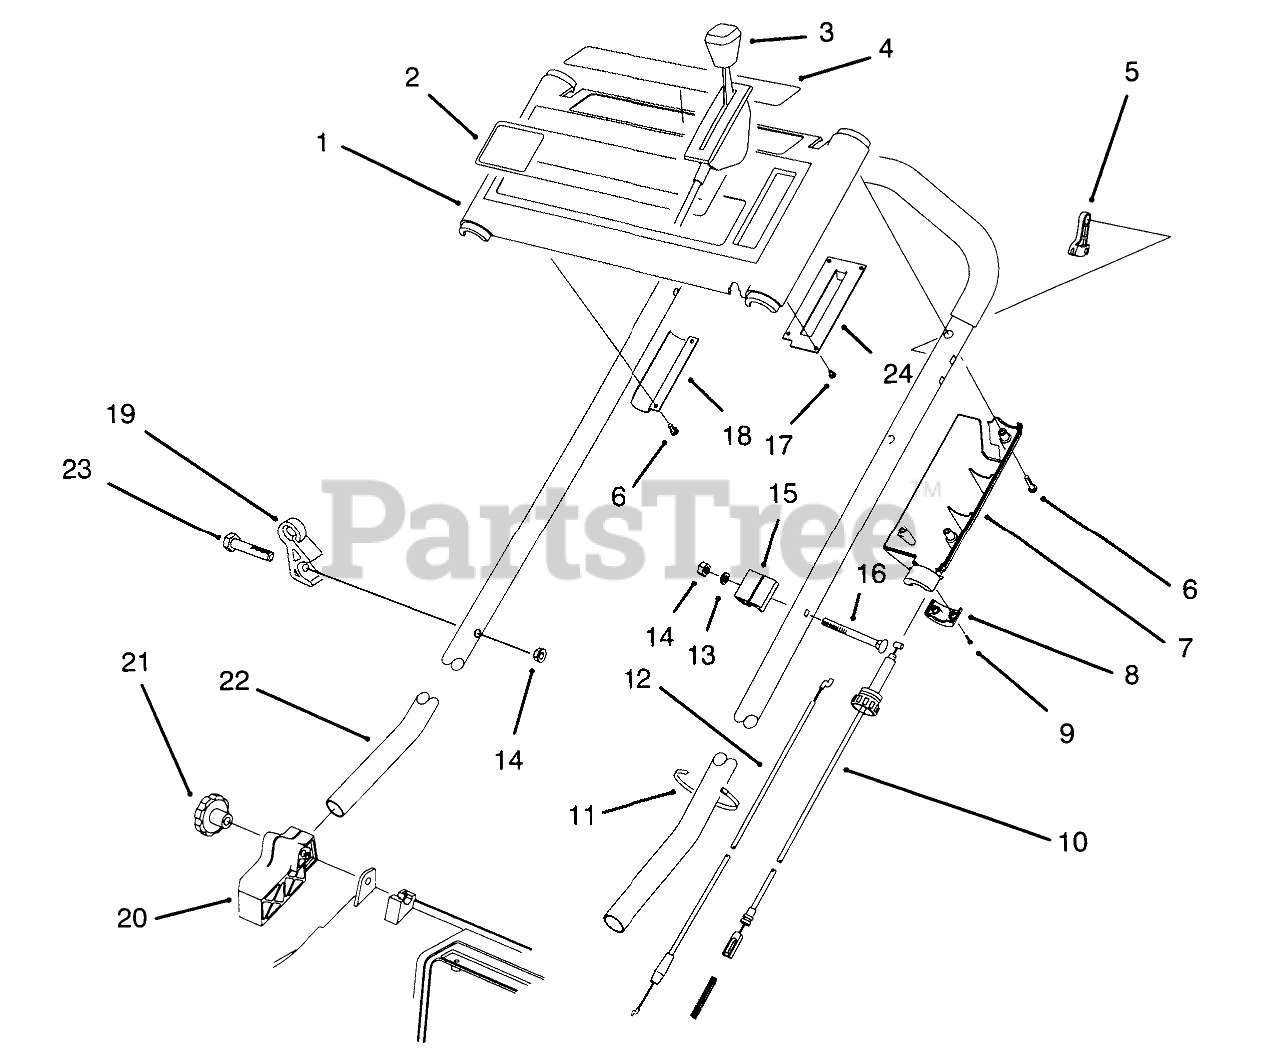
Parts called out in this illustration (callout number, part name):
1	Panel-Control(Incl Ref. #2,4)
2	DECAL - PANEL OHV
3	CONTROL - THROTTLE
4	DECAL - INSTRUCTION
5	LEVER-TRACTION
6	SCREW-PPH, PLASTITE
7	COVER-THROTTLE, LEVER
8	LOWER THROTTLE CAP
9	#4-14X.62 PLASTITE SCW
10	CABLE - TRACTION
11	TIE-CABLE
12	CABLE - BRAKE
13	WASHER-FLAT
14	NUT-LOCK, NI
15	SUPPORT-CABLE
16	SCREW-HANDLE
17	#6-19X.25 PLASK FORM SC
18	Bracket-Panel
19	GUIDE - ROPE
20	MOUNT-HANDLE, RH
22	HANDLE (DIPPED)
23	.250-20X1.625 HH SCREW
24	THROTTLE PLATE
